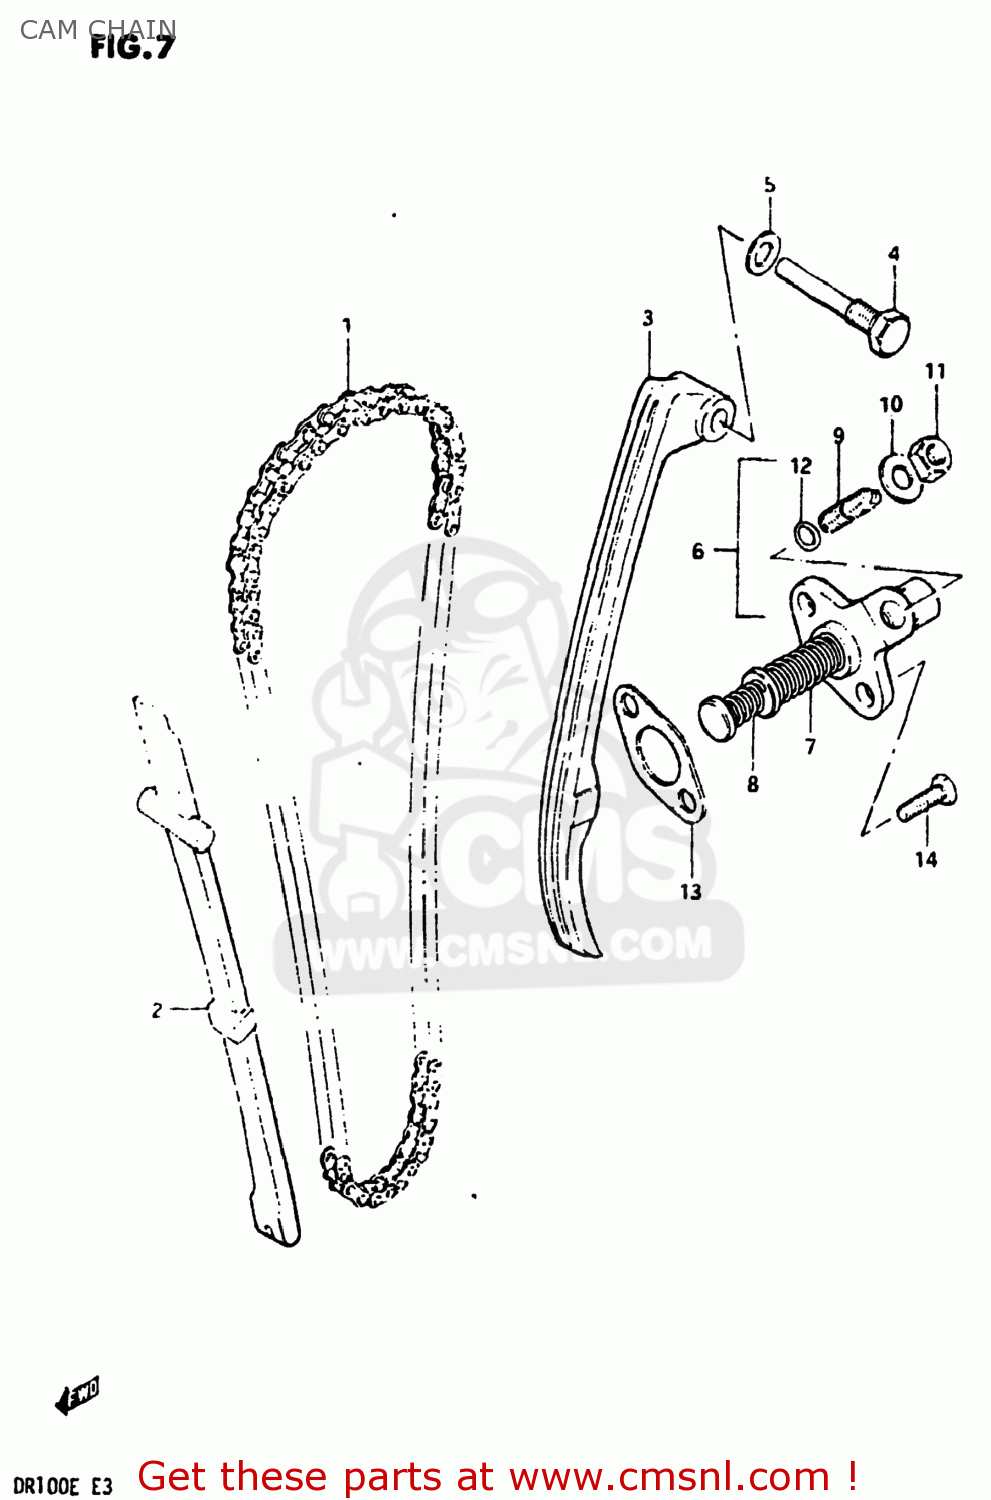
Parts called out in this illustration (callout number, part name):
1	CHAIN,CAMSHAFT DRIVE
2	GUIDE,CAM CHAIN
3	TENSIONER,CAM CHAIN
4	BOLT,CAM CHAIN TENSIONER
5	GASKET 8.2X14X1 (NAS)
6	ADJUSTER ASSEMBLY,TENSIONER
7	SPRING
8	SPRING
9	SCREW
10	WASHER,8.5X16X
11	NUT
12	O RING(D:1.9,ID:5.7)
13	GASKET,TENSIONER ADJUSTER (NAS)
14	BOLT
